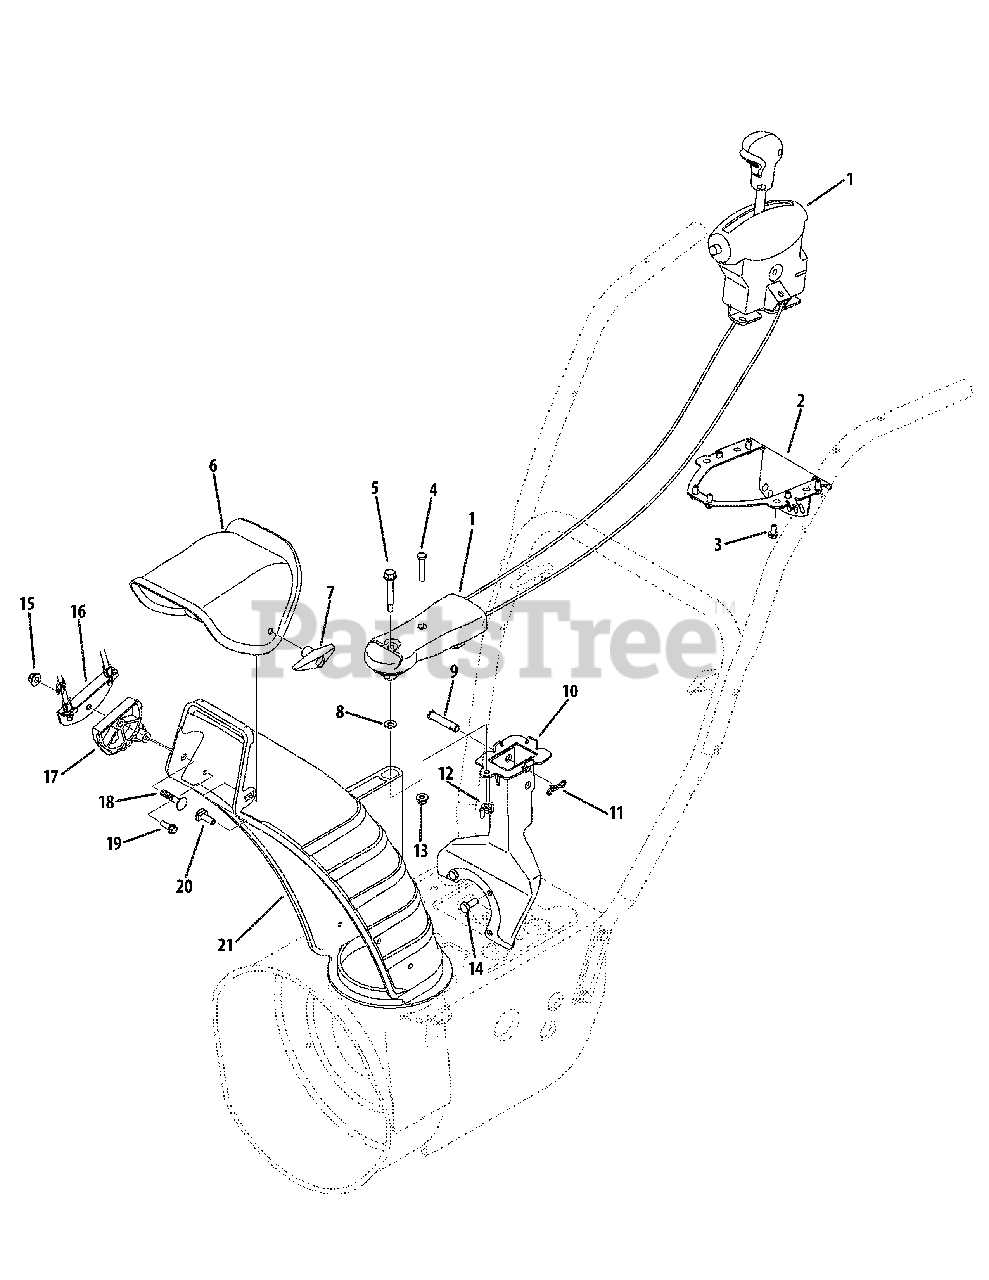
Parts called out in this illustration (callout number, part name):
1	Chute Control Assembly, 4-Way
3	Hex Washer Screw, 1/4-15 x .50
4	Hex Screw, 1/4-20 x 1.50
5	Shoulder Screw, .312 x 1.70 x /-20
6	Upper Chute
7	Wing Knob, 5/16-18
8	Flat Washer, .25 x .630 x .0515
9	Clevis Pin, 3/8 x 1.87
10	Chute Support Bracket
11	Bow-Tie Cotter Pin
12	Wing Nut, 1/4-20
13	Flange Lock Nut, 1/4-20
14	Hex Lock Screw, 5/16-24 x .750
15	Flange Lock Nut, 5/16-18
16	Cable Bracket
17	Chute Tilt Cable Guide
18	Carriage Bolt, 5/16-18 x 1.50
19	Hex Washer Screw, 1/4-15 x .750
20	Carriage Bolt, 5/16-18 x 1.00
21	Lower Chute, 5.0
